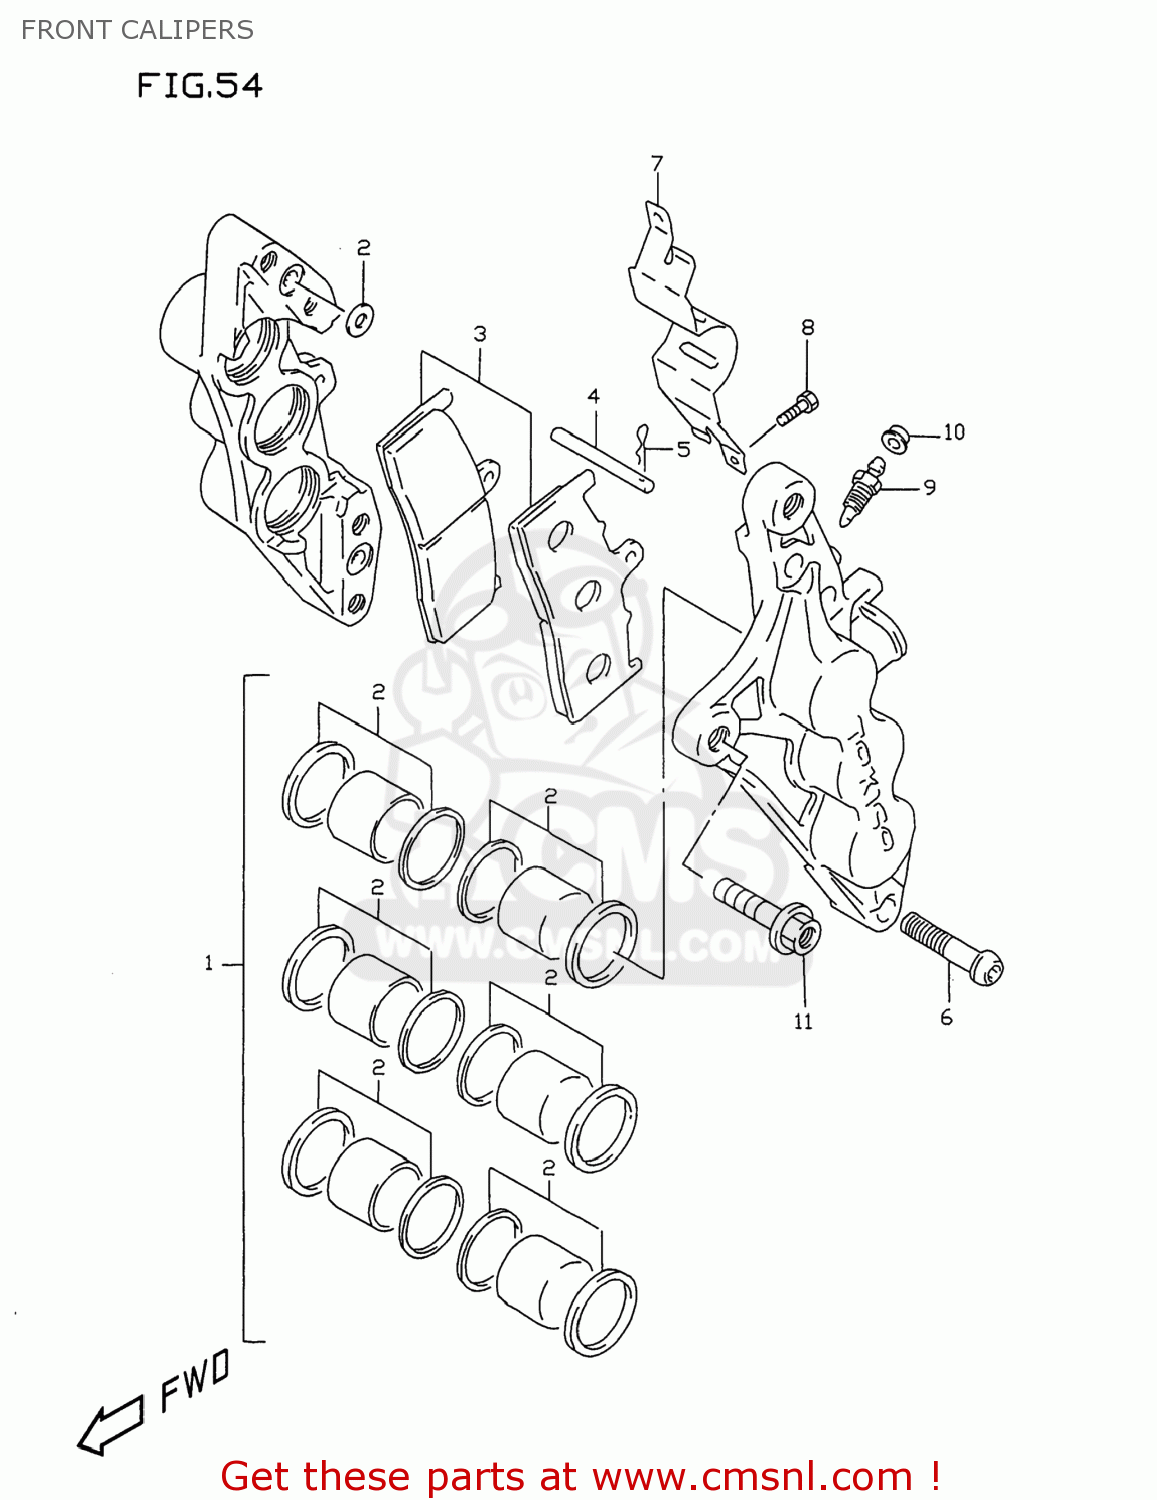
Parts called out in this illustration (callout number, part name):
1	PISTON SET
2	SEAL SET,PISTON
3	PAD SET (NAS)
4	PIN,PAD
5	CLIP,PAD PIN
6	BOLT,HOUSING
7	COVER,CALIPER
8	SCREW
9	BLEEDER
10	CAP,BLEEDER PLUG
11	BOLT(10X30)
